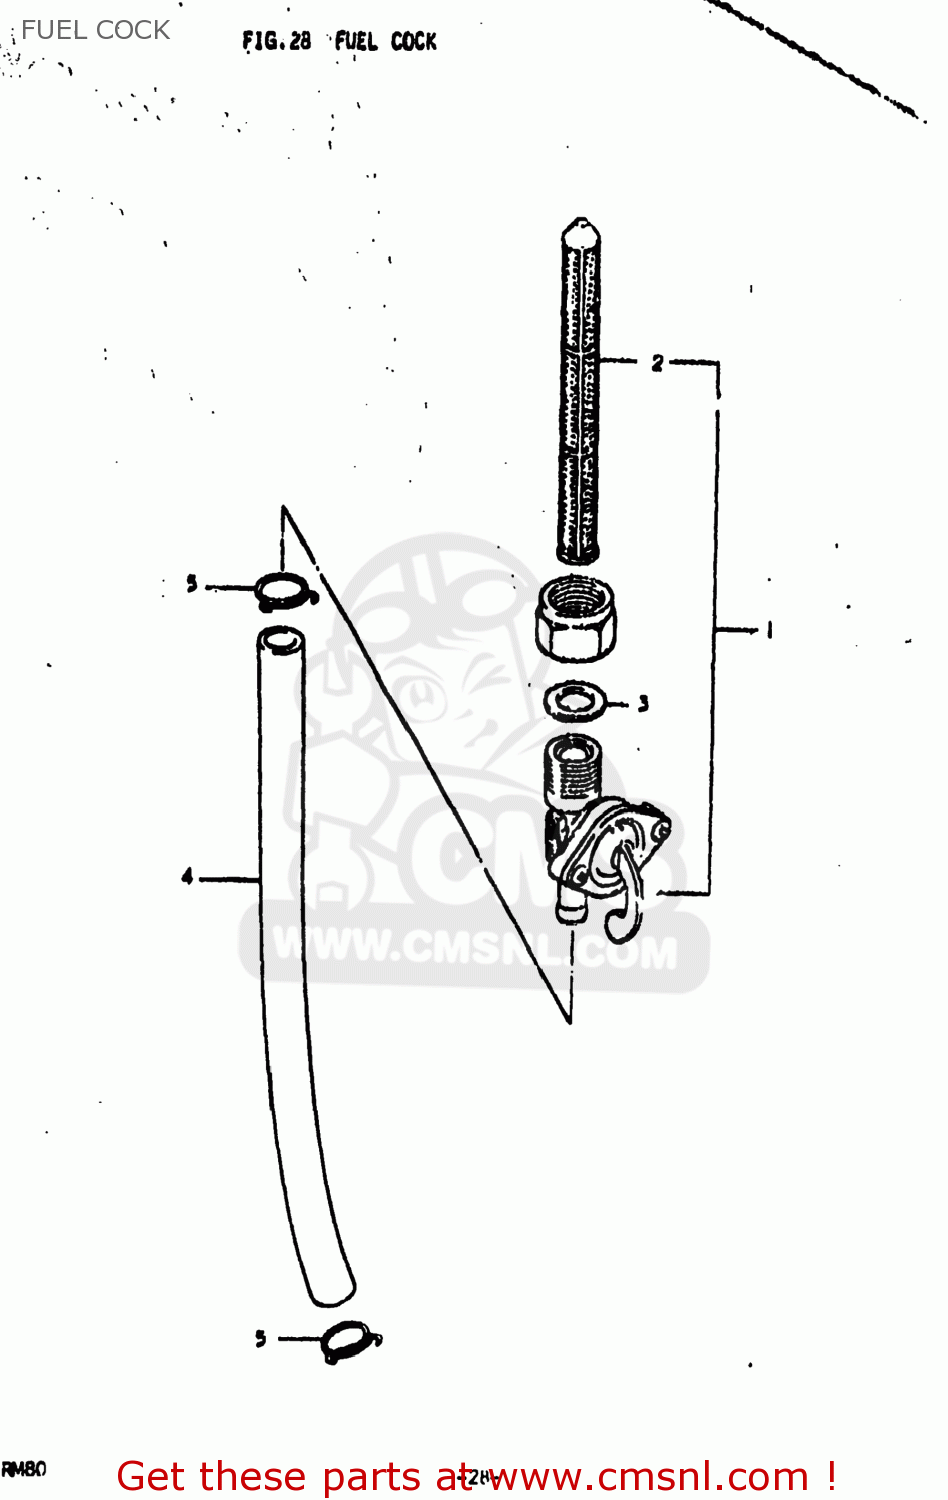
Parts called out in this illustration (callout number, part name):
1	COCK ASSY,FUEL
2	FILTER,FUEL
3	GASKET,FUEL COCK (NAS)
4	HOSE
5	CLIP
